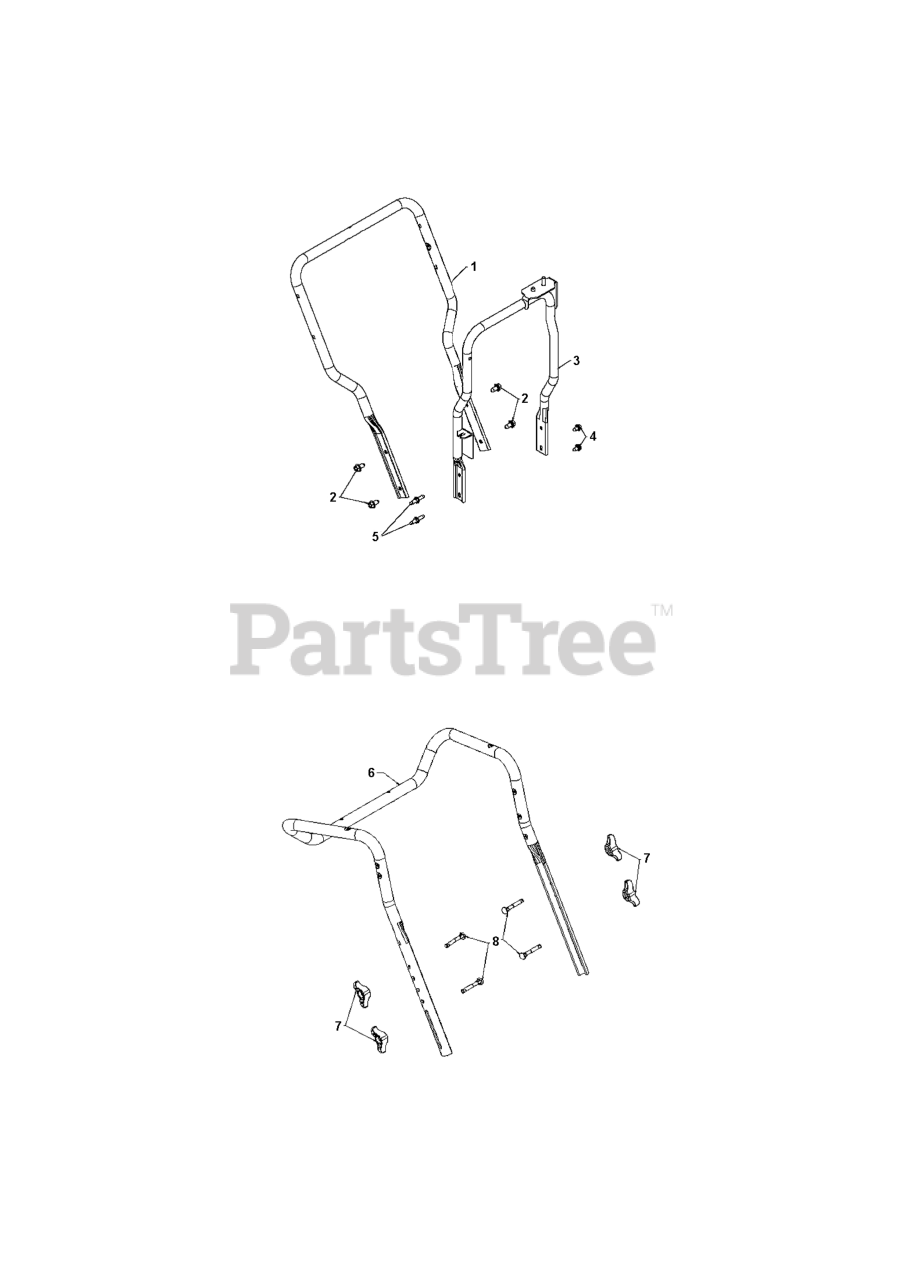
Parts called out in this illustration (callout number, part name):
1	HANDLE.LOWER.498
2	SCREW, 3/8-16X3/4
3	SUPPORT WELDMENT, CHUTE PAINTE
4	BOLT.5/16HEX.WHS.HD
5	STUD BOLTED HEX HEAD
6	HANDLE.UPPER.498
6	HANDLE.UPPER.479
7	KNOB, DEFLECTOR
8	BOLT.CARRIAGE.5/16-18 X 2.25
